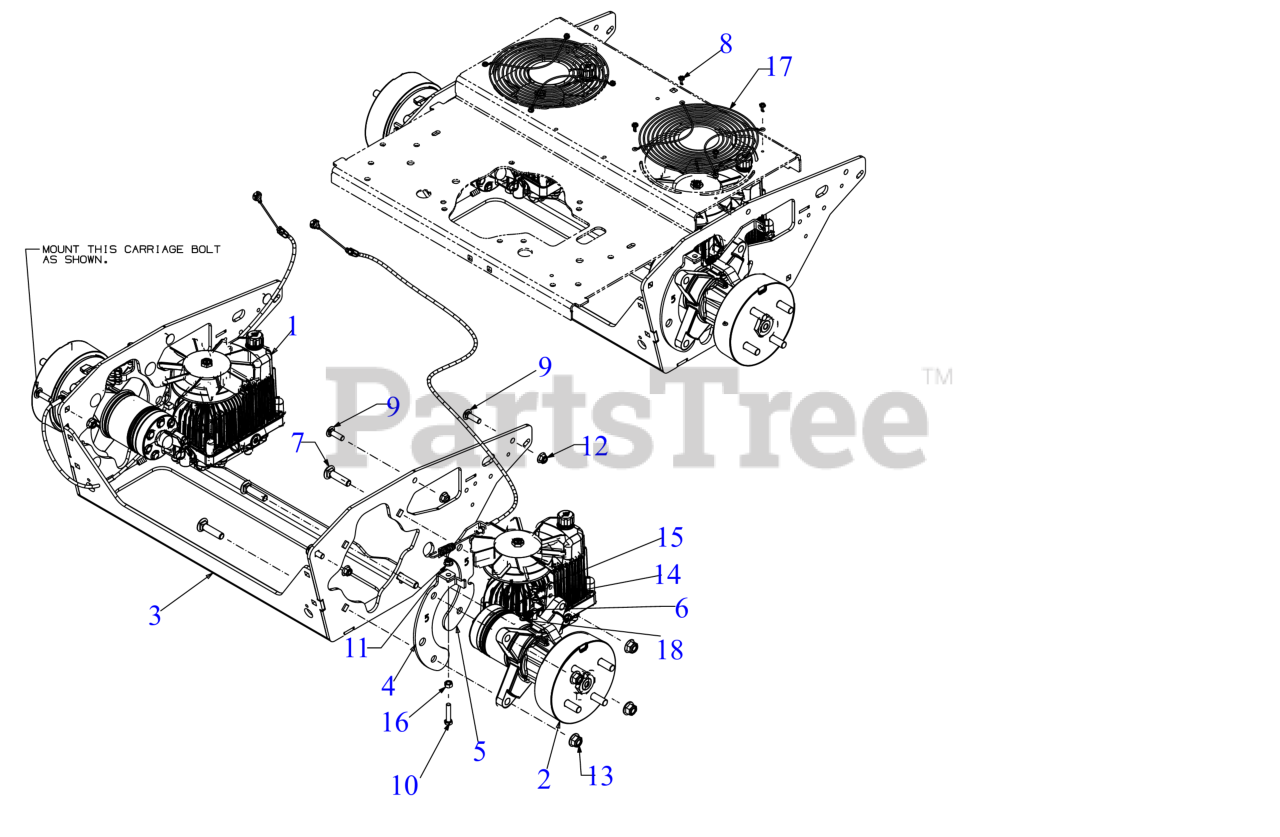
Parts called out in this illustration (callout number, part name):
1	TRANSMISSION / MOTOR ASSEMBLY (LH)
2	TRANSMISSION / MOTOR ASSEMBLY (RH)
3	TRANSMISSION MOUNTING BRACKET
6	SCREW 5/16-18 x 1.0 GR5
7	CARRIAGE BOLT 1/2-13 GR5
8	SCREW 10-24 x 0.500
9	CARRIAGE BOLT 3/8-16 X1.25 GR5
10	SCREW 5/16-18 x 1.5 LG
11	FLANGE LOCK NUT 5/16-18
15	HEX NUT LOCK CENTER
16	HEX NUT 5/16-18
18	EXTENSION SPRING .500 OD x 1.71
